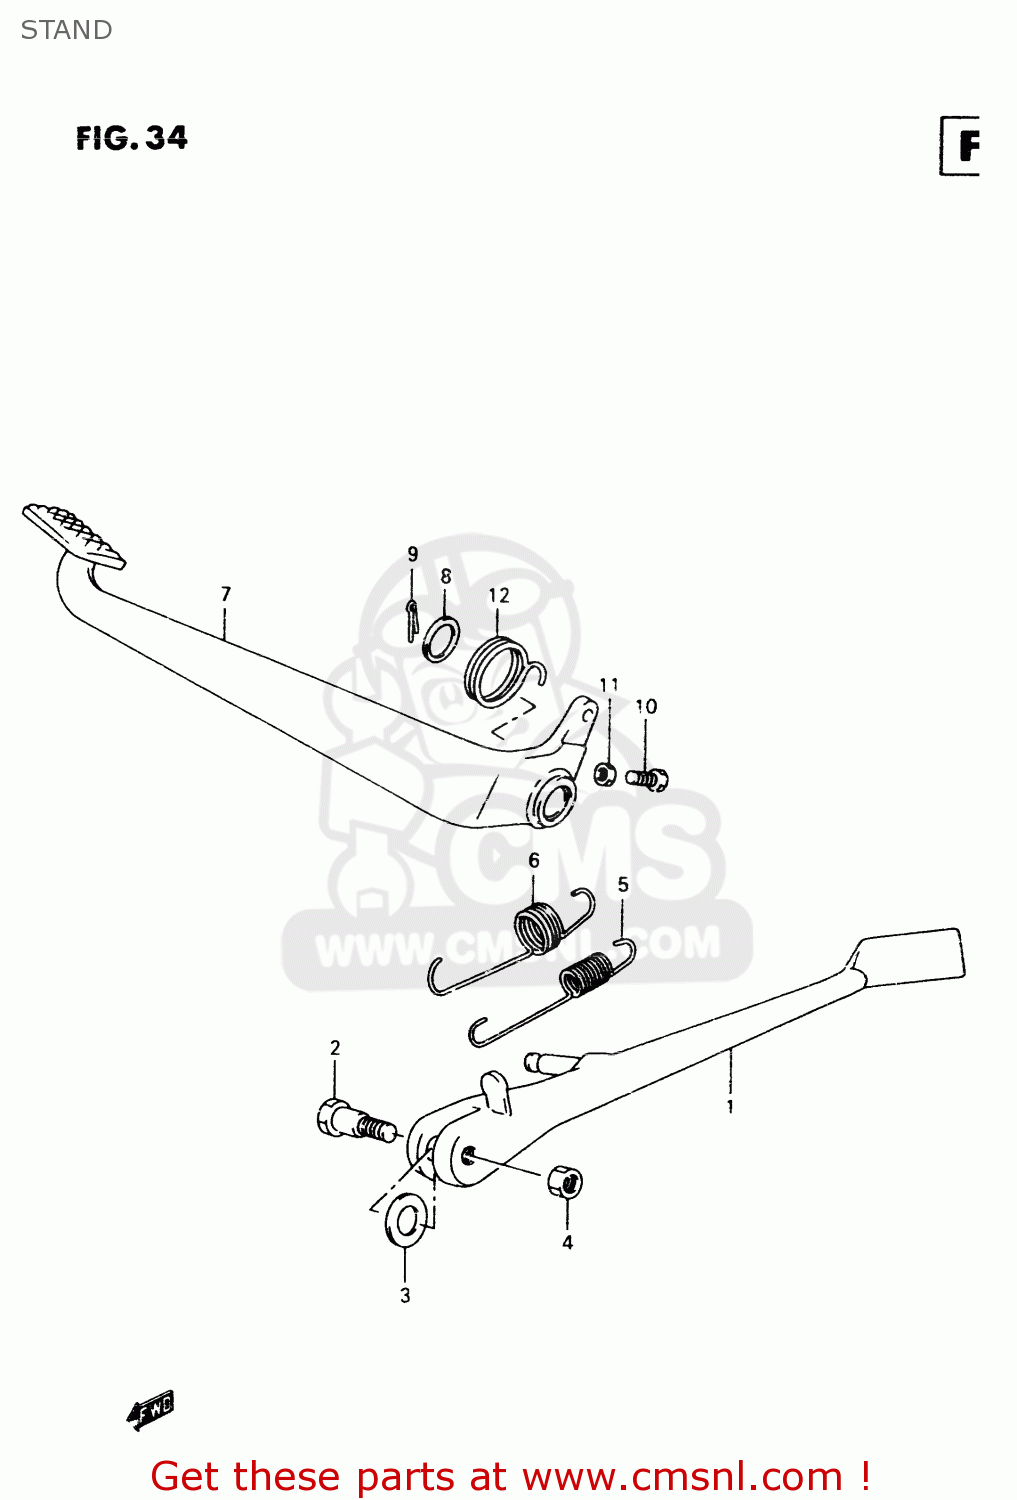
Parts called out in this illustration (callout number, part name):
1	STAND, PROP
2	BOLT(10X34)
3	SHIM
4	NUT
5	SPRING
6	SPRING
7	PEDAL COMP,BRAKE
8	WASHER(16.5X22X1)
9	COTTER PIN
10	BOLT
11	NUT
12	SPRING
